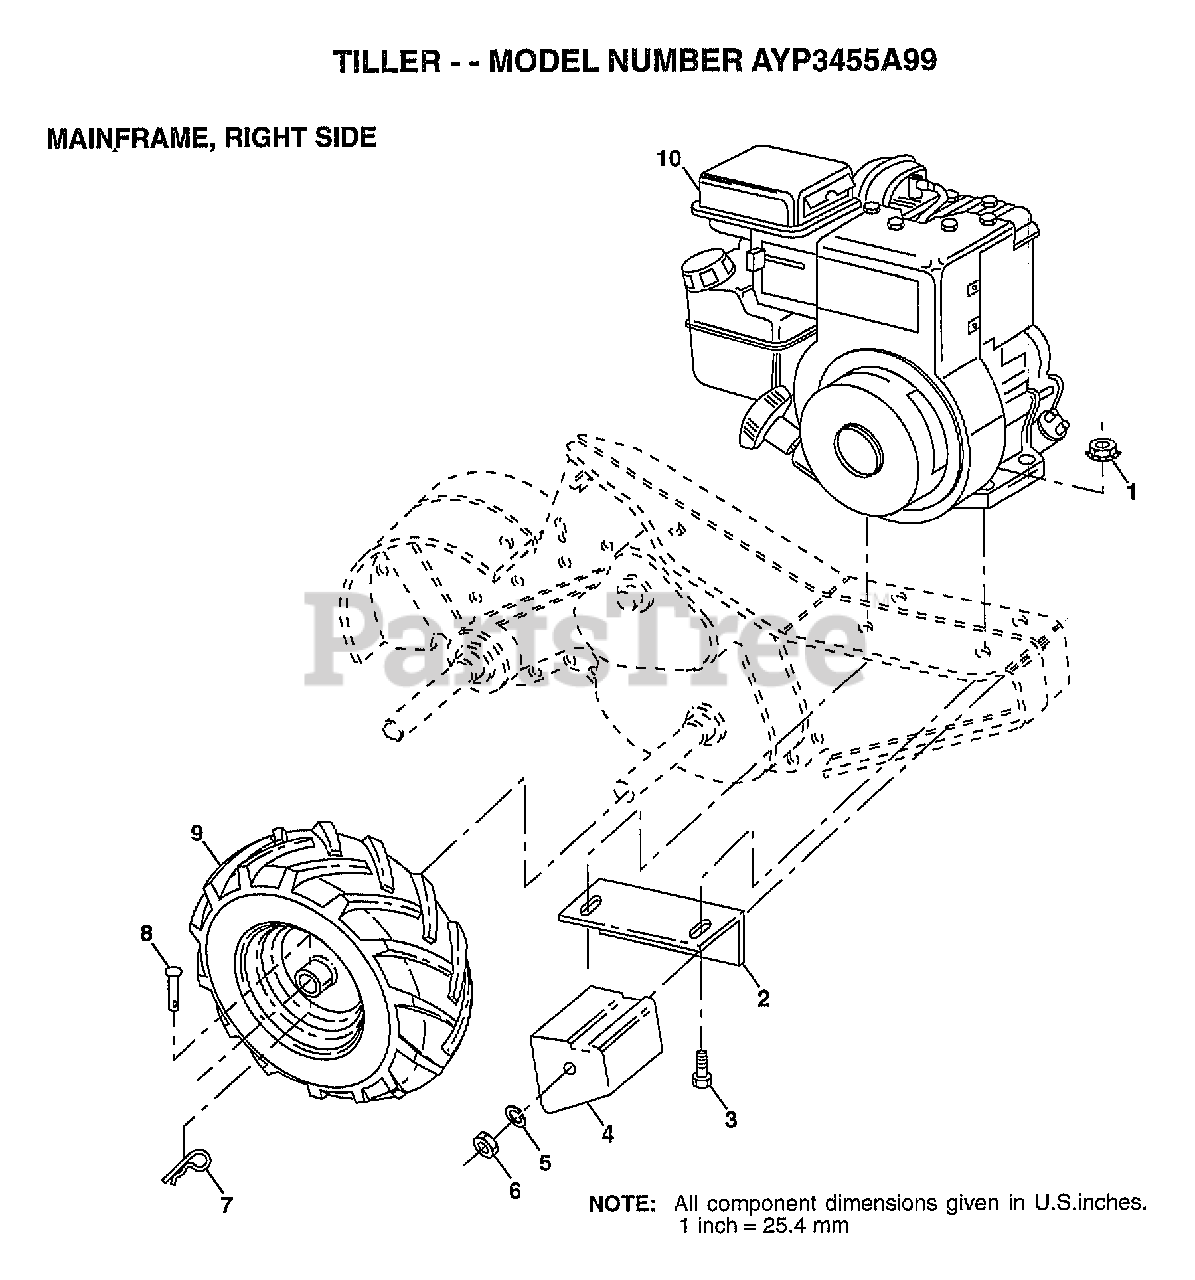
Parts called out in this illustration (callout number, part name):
2	BRACKET RH CRT
3	BOLT.HEX.5/16-1.5
4	COUNTERWEIGHT CRT
5	LOCKWASHER
6	NUT.HEX.3/8-16UNC
7	RETAINER M
8	RIVET.DRILL.1.75
9	TIRE TI
9	RIM
